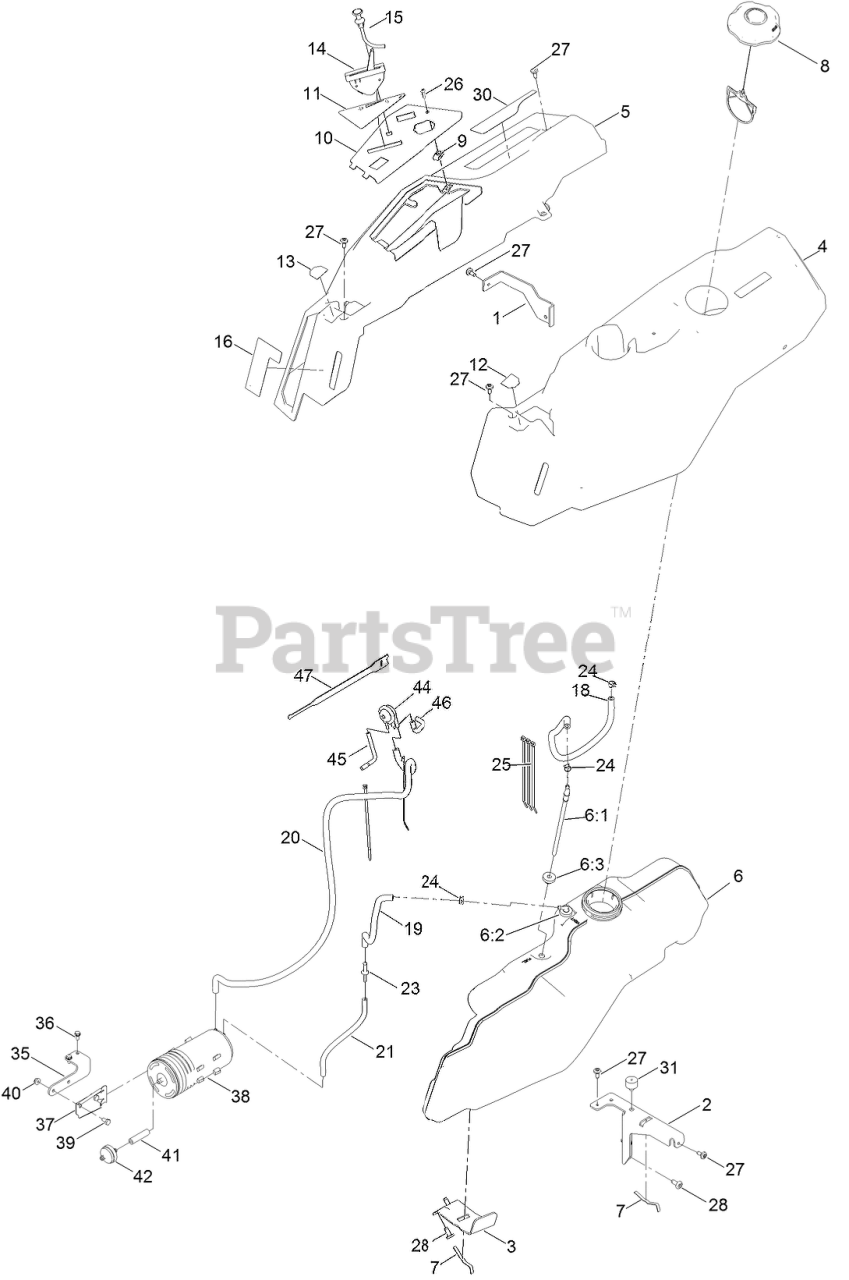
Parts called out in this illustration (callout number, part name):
1	BRACKET-POD
2	SUPPORT-POD, LH
3	SUPPORT-TANK, FUEL
4	POD-LH
5	POD-RH, MYRIDE
6	FUEL TANK ASM
6:1	CONNECTOR-ELBOW, 90 DEG
6:2	FITTING-PLASTIC
6:3	BUSHING
7	SPRING
8	CAP-FUEL, RATCHETING
10	PANEL - CONTROL
11	DECAL-PANEL, CONTROL
12	DECAL-CONTROL LEVER, LH
13	DECAL-CONTROL LEVER, RH
14	CABLE-THROTTLE
15	CABLE-CHOKE
16	DECAL-SMART SPEED
18	HOSE-FUEL
19	HOSE-FUEL
20	HOSE-FUEL
21	HOSE-FUEL
23	ADAPTOR-ORIFICE
24	CLAMP-HOSE
25	TIE-CABLE
26	SCREW-PRH
27	SCREW-SHOULDER
30	DECAL-ADJUSTMENT
31	BUMPER-GROMMET
35	BRACKET-CANISTER, CARBON
36	SCREW-HWH
37	BRACKET-CANISTER, CARBON
38	CANISTER-CARBON, 800CC
39	SCREW-HH
40	NUT-HF
41	HOSE-FUEL
42	FILTER-FUEL, INLINE
44	VALVE-CONTROL, VACUUM
45	HOSE-VENT, FORMED
46	HOSE-VENT, FORMED
47	STRAP-VELCRO, CABLE TIE
